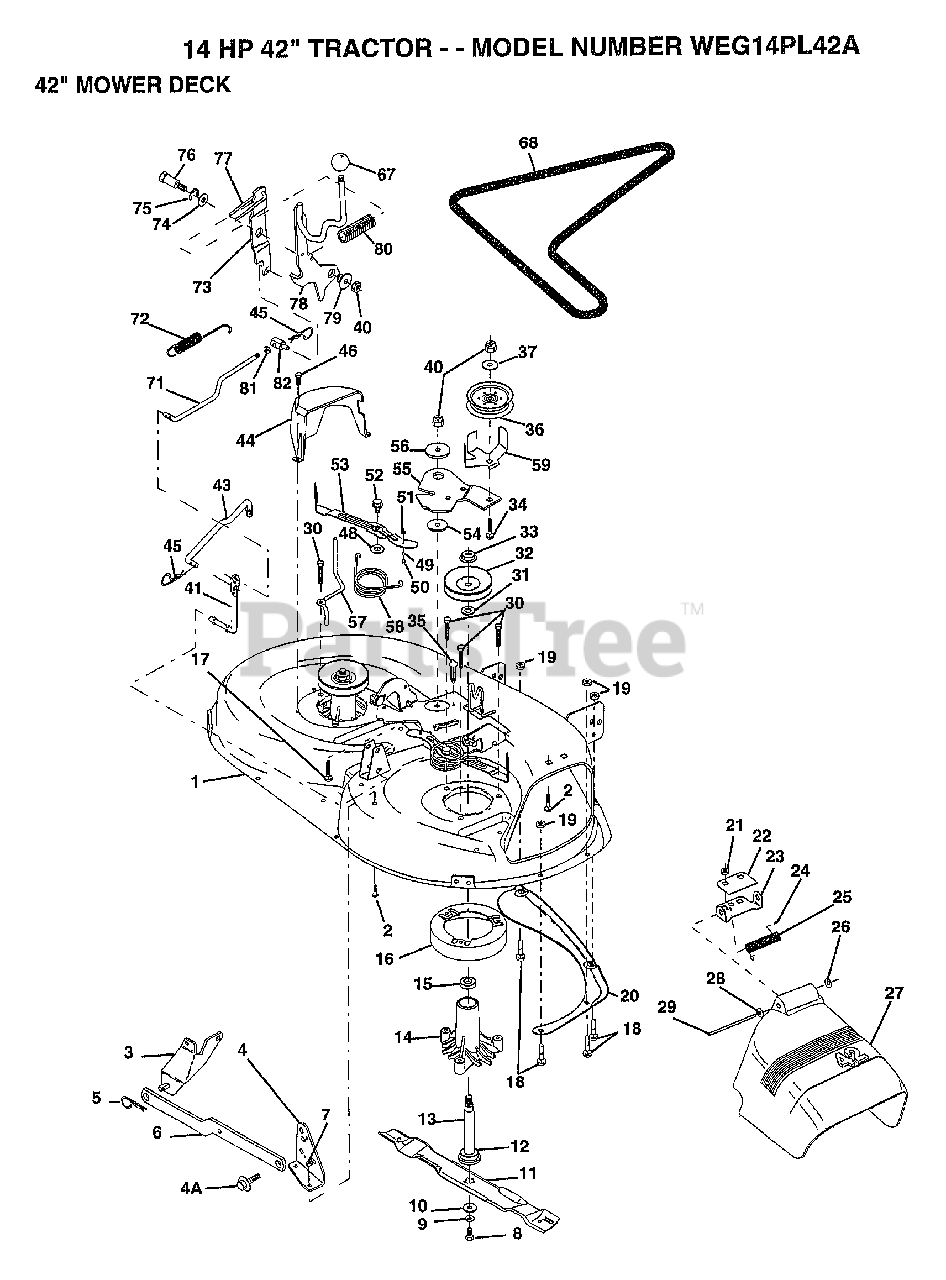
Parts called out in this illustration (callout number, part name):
2	BOLT
3	BRKT ASM SWAY BAR
4	BRKT DECK SW BAR
4A	BOLT SHD 5/16-18
7	NUT
8	BLADE BOLT
10	WASHER.HARD.BLADE
11	"BLADE.42"" MULCHER"
12	BEARING.BALL
14	HSG ASM MANDREL
15	BEARING
16	STRIPPER RND MWR
17	BOLT RDHD 3/8-16
18	BOLT
19	NUT
21	NUT
22	STIFFENER BRKT
23	DEFLECTOR BRKT
24	CAP-SLEEVE LT
25	SPRING TORSION
26	NUT PUSH M
27	DEFLECTOR.SHIELD
28	WASHER
29	HINGE ROD
31	WASHER
34	BOLT
35	XMAS TREE FASTNER
36	FLAT IDLER PULLEY
37	WASHER
40	NUT
41	PIVOT ROD
43	ROD CLUTCH W/NIBS
44	GUARD MAND LH BLK
45	RETAINER M
46	SCREW.1/4-20X5/8
48	HARD SMALL WASHER
50	SHOULDER BOLT
51	LOCKNUT
52	BOLT.SHLD.5/16-18
53	BRAKE PAD ARM ASM
54	HARDENED WASHER
56	SPACER RETAINER
57	KEEPER BELT LH 42
58	SPRING TORSN BRAK
59	GUARD IDLER TUV
68	BELT-V MWR 82.625
71	ROD CLUTCH 38/42
72	RETURN SPRING
73	CLUTCH ARM SECOND
74	WASHER
75	RING
76	SHOULDER BOLT
77	SPRING KEEPER
78	LEVER ASM CLT PRM
79	BUSHING
81	NUT
82	TRUNION ADJ
83	KNOB T (1/2-HOLE)
